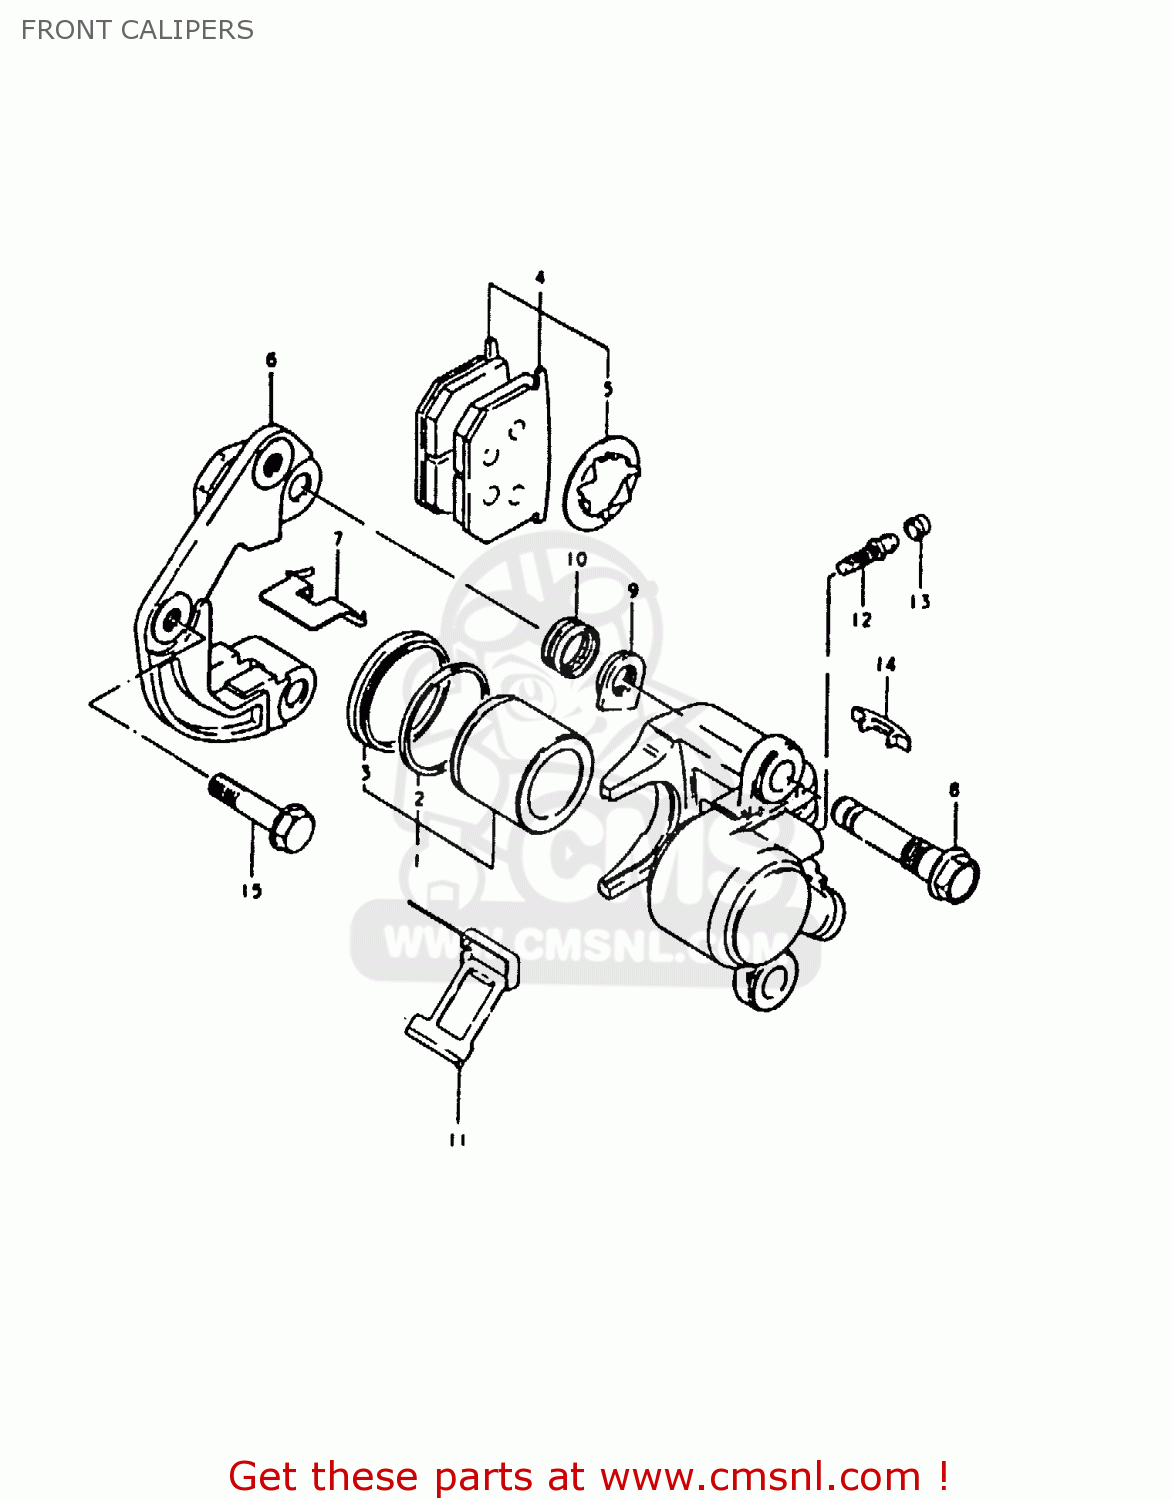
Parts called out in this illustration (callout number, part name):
1	PISTON SET
2	SEAL,PISTON
3	BOOT,PISTON
4	PAD & SHIM SET (MCA)
5	SHIM,PAD
6	HOLDER,CALIPER,LEFT
7	GUIDE,PAD
8	AXLE,CALIPER
9	NUT,CALIPER AXLE
10	BOOT
11	SPRING
12	BREATHER
13	CAP,BLEEDER PL
14	COVER,INDICATOR
15	BOLT(10X37)
